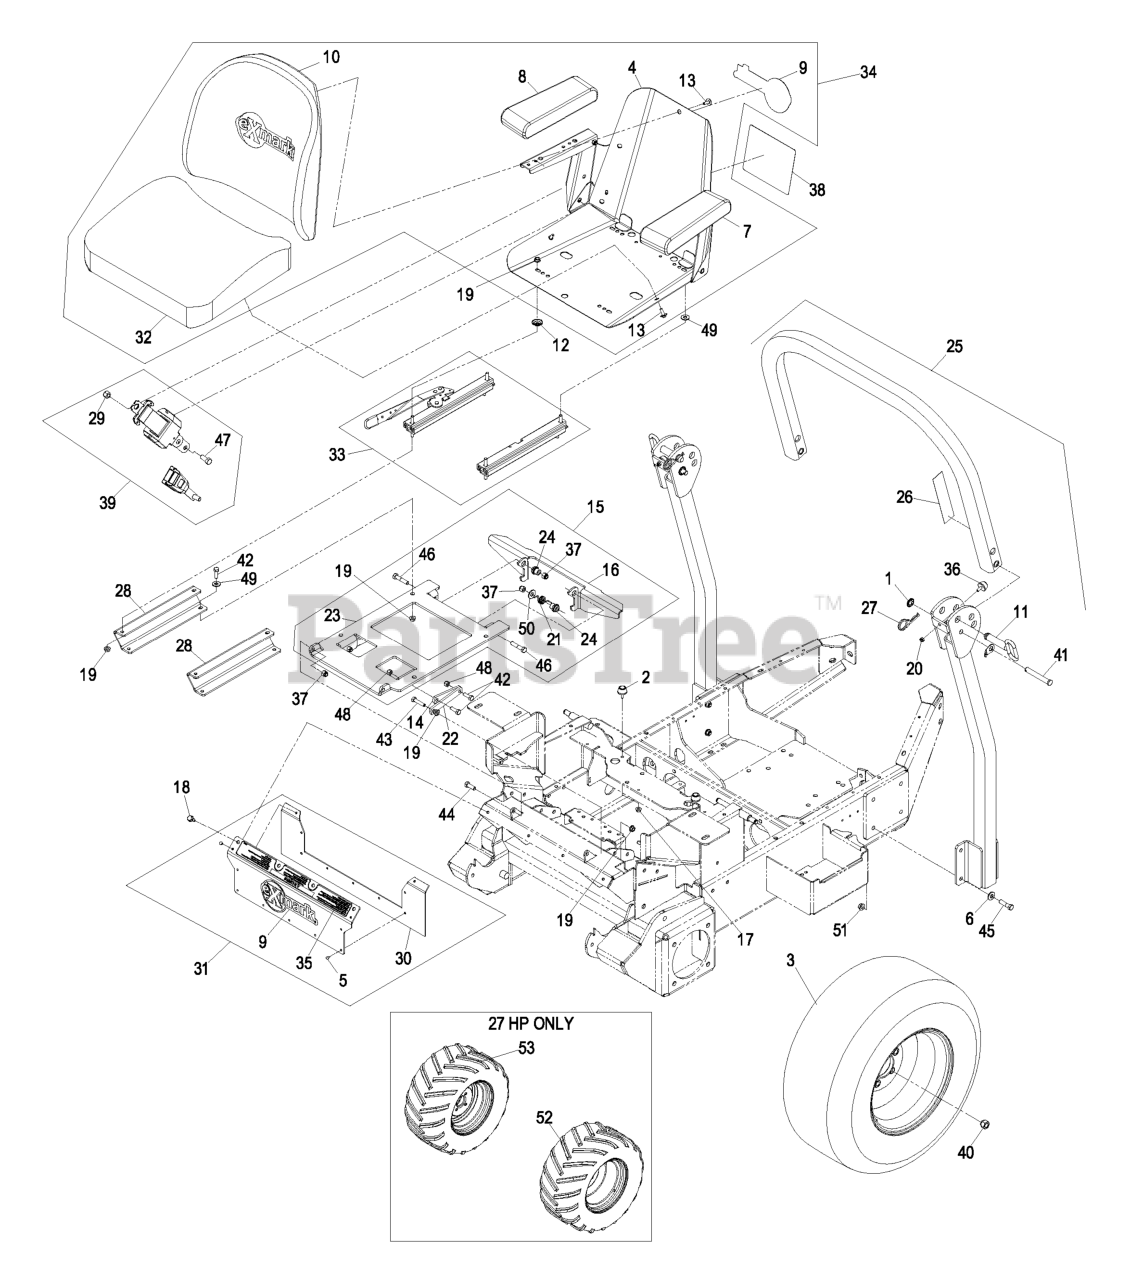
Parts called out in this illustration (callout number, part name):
1	NUT-PUSH
4	FRAME-SEAT
5	RIVET-POP
6	WASHER-BELLEVILLE
7	CUSHION,ARMREST LH
8	CUSHION,ARMREST RH
9	DECAL,EXMARK LOGO
10	CUSHION,SEAT BACK
11	PIN-FOLD, ROPS
12	SPACER-TRACK
13	BOLT-SEAT
14	LINK-STOP, SEAT
15	ASM, SEAT FRAME FMZ
18	SCREW-HWH, THREAD CUT
20	NUT-LOCK, NI
22	LINK,FMZ LWR SEAT STOP (P
24	BUSHING-LATCH, SEAT
25	KIT,ROPS FMZ
26	DECAL-WARNING, FOLDING RO
27	HAIRPIN
28	Spacer, Seat Mount
29	NUT-LOCK
30	Skirt, Rubber
31	ASM,FRONT COVER W/DECAL
35	DECAL,TOP CONSOLE
36	BUMPER-RUBBER
37	NUT-LOCK, NI
38	Decal, Service Aid
40	NUT-LUG
41	PIN-CLEVIS
42	SCREW-HH
43	SCREW-HH
44	SCREW-HH
45	SCREW-HH
46	SCREW-HH
47	SCREW-HH
48	NUT-LOCK, NI
49	WASHER-FLAT
50	WASHER-FLAT
51	NUT-HHF, WHIZ
52	Asm, Wheel & Tire (Lh) 27hp
53	Asm, Wheel & Tire (Rh) 27hp
